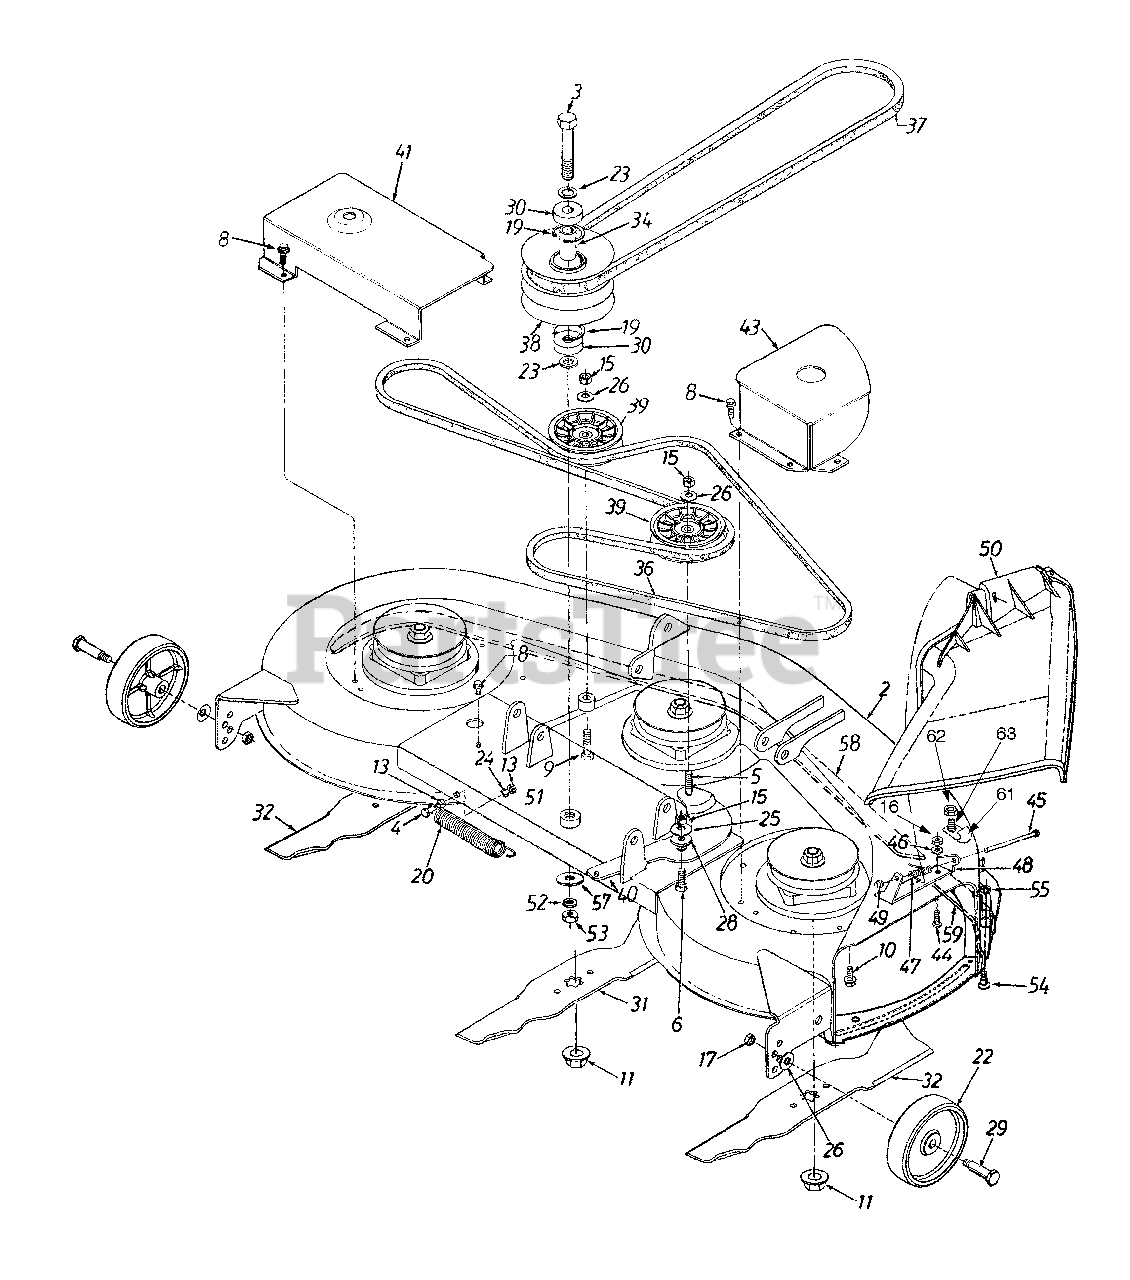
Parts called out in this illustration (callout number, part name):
4	Hex Bolt 1/4-28 x 1.25" Lg.
5	Hex Bolt 3/8-24 x 1.5" Lg.
6	Hex Bolt 3/8-24 x 1" Lg.
8	Hex Wash. Hd. TT-Tap Scr.1/4-20 x .5"
9	Hex Bolt 3/8-24 x 2" Lg.
10	Hex Flange Bolt 5/16-24 x .75" Lg.
11	Hex Flange L-Nut 5/8-18 Thd.
13	Hex Nut 1/4-28 Thd.
15	Hex Nut 3/8-24 Thd.
16	Hex Nut 1/4-20 Thd. (Gr. 5)
17	Hex Top Jam Nut 3/8-16 Thd.
19	Int. Snap Ring
20	Ext. Spring .88" O.D. x 6.17"
23	Fl-Wash. .635" I.D. x 1" O.D. x.06"
24	L-Wash. 1/4" I.D.
25	Bell-Wash. 3/8" x 1.125" x .062"
26	Bell-Wash. 3/8" x .87" x .064"
28	Shoulder Spacer .625" I.D. x .169"
29	Shld. Bolt .498" x 1.525"
30	Ball Brg. .625" I.D. x 1.574" O.D. x .47"
31	Blade 14.88" Lg.
32	Blade 16.28" Lg.
34	Spacer .635" I.D. x .088" O.D.
36	V-Belt
37	V-Belt
38	Pulley Double Deck 5" O.D.
39	Flat Idler Pulley 3.5 O.D.
44	Hex Bolt 1/4-20 x .62" Lg.
45	Hinge Pin
46	Bell-Wash. 1/4" I.D.
47	Torsion Spring
48	Hinge Mtg. Brkt.
50	Chute Ass'y.
51	Spacer .635" I.D. x 1" O.D.
52	L-Wash. 5/8" I.D.
53	Hex Nut 5/8-18 Thd.
54	Carriage Bolt 1/4-20 x .5" Lg.
55	Hex Sems Nut 1/4-20 Thd.
57	Fl-Wash. .635" I.D.
61	Retainer Hook Bracket
62	Hex Lock Nut 1/4-20
63	Hex Cap Screw 1/4-20 x .620
